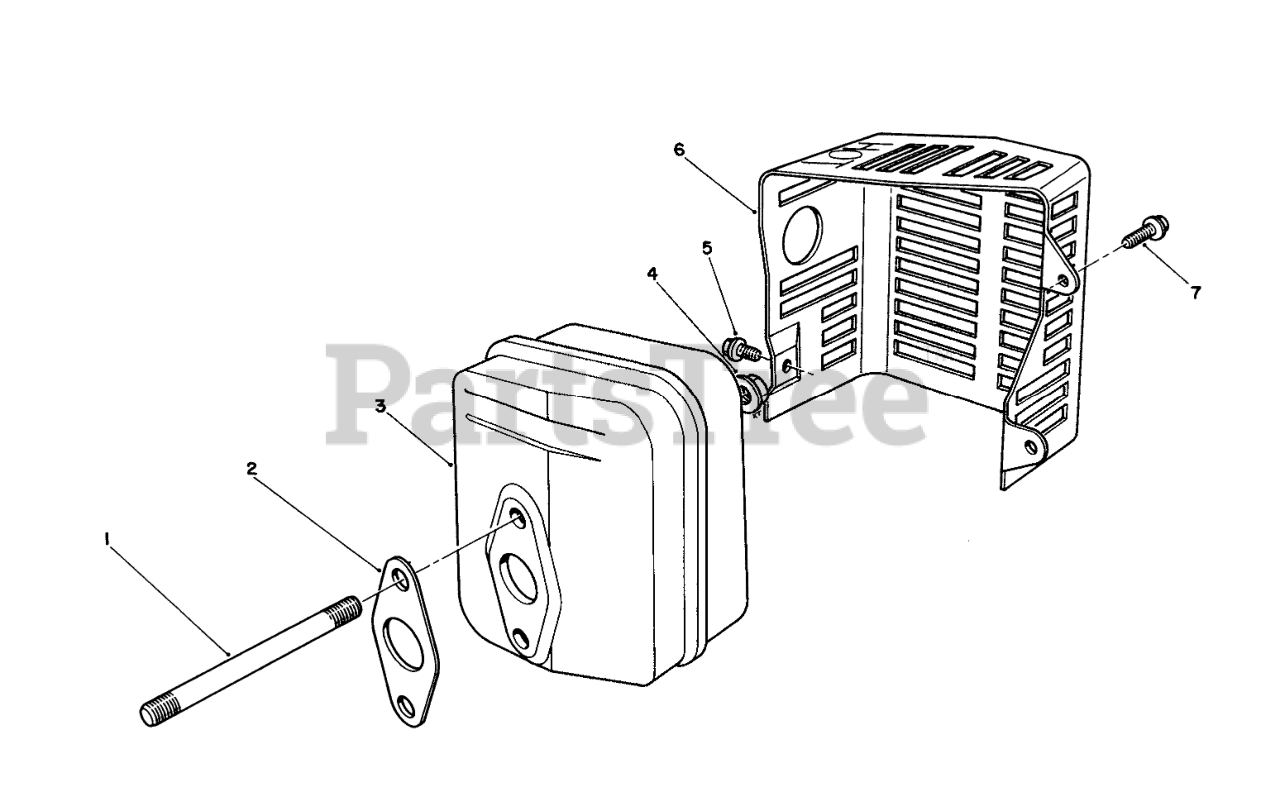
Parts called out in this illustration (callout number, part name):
2	GASKET
3	MUFFLER
5	SCREW
6	COVER
